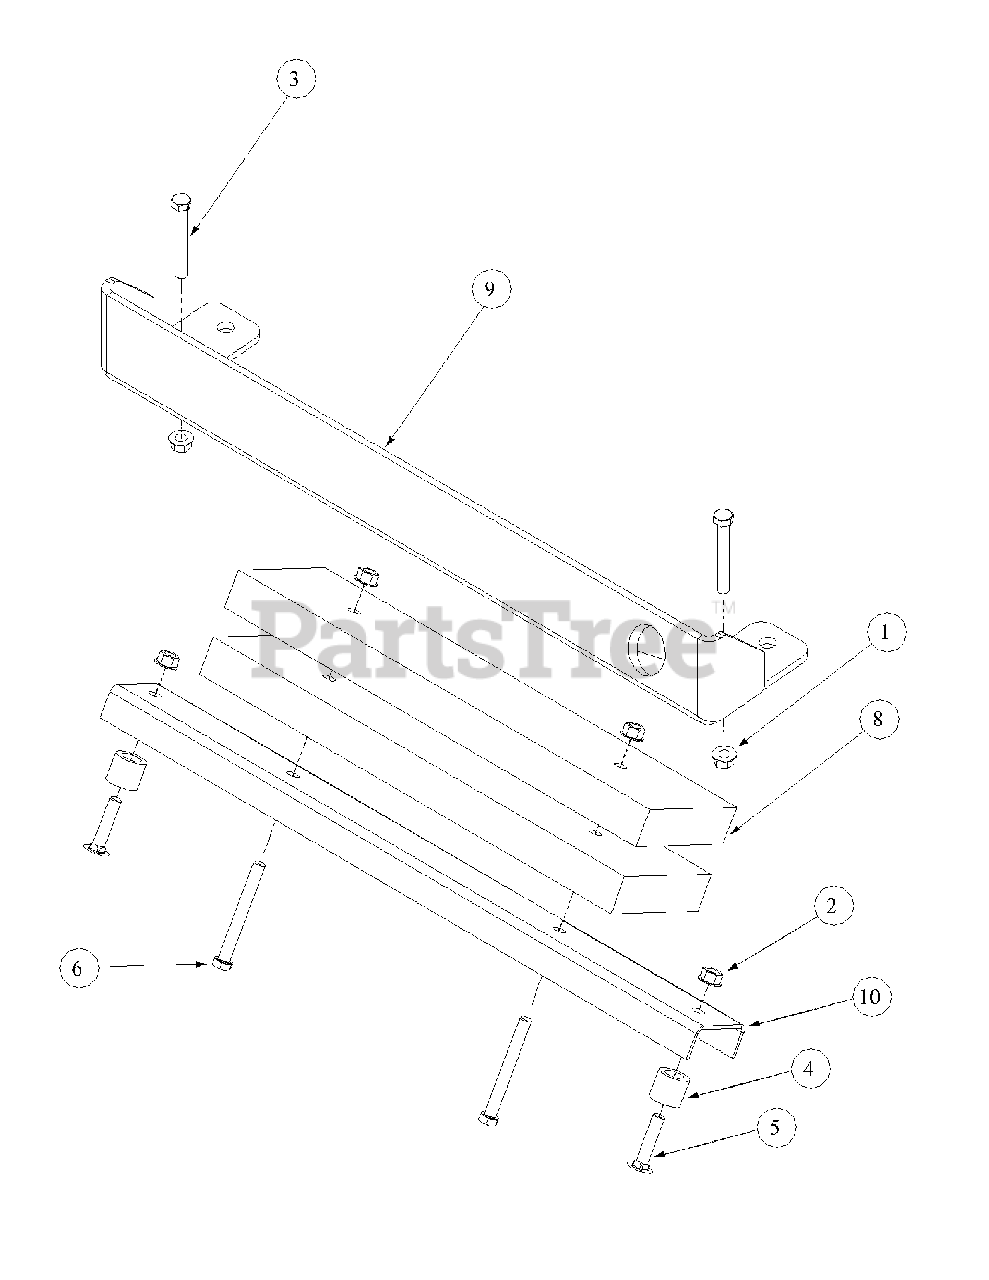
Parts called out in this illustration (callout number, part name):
1	Hex Nut, 1/2-13, Insert Lock
2	Nut, Hex 3/8-16 Flange Lock
3	HHCS, 1/2-13, 3.00
4	Spacer Crossbar
5	Carriage Bolt, 3/8-16, 1.75
5	Carriage Bolt; 3/8-16 x 2.75
6	HHCS, 3/8-16, 3.25
8	Bar, Weight w/o Spacers
9	Rear Bumper Plate
10	Bumper Cross Bar-Rear
